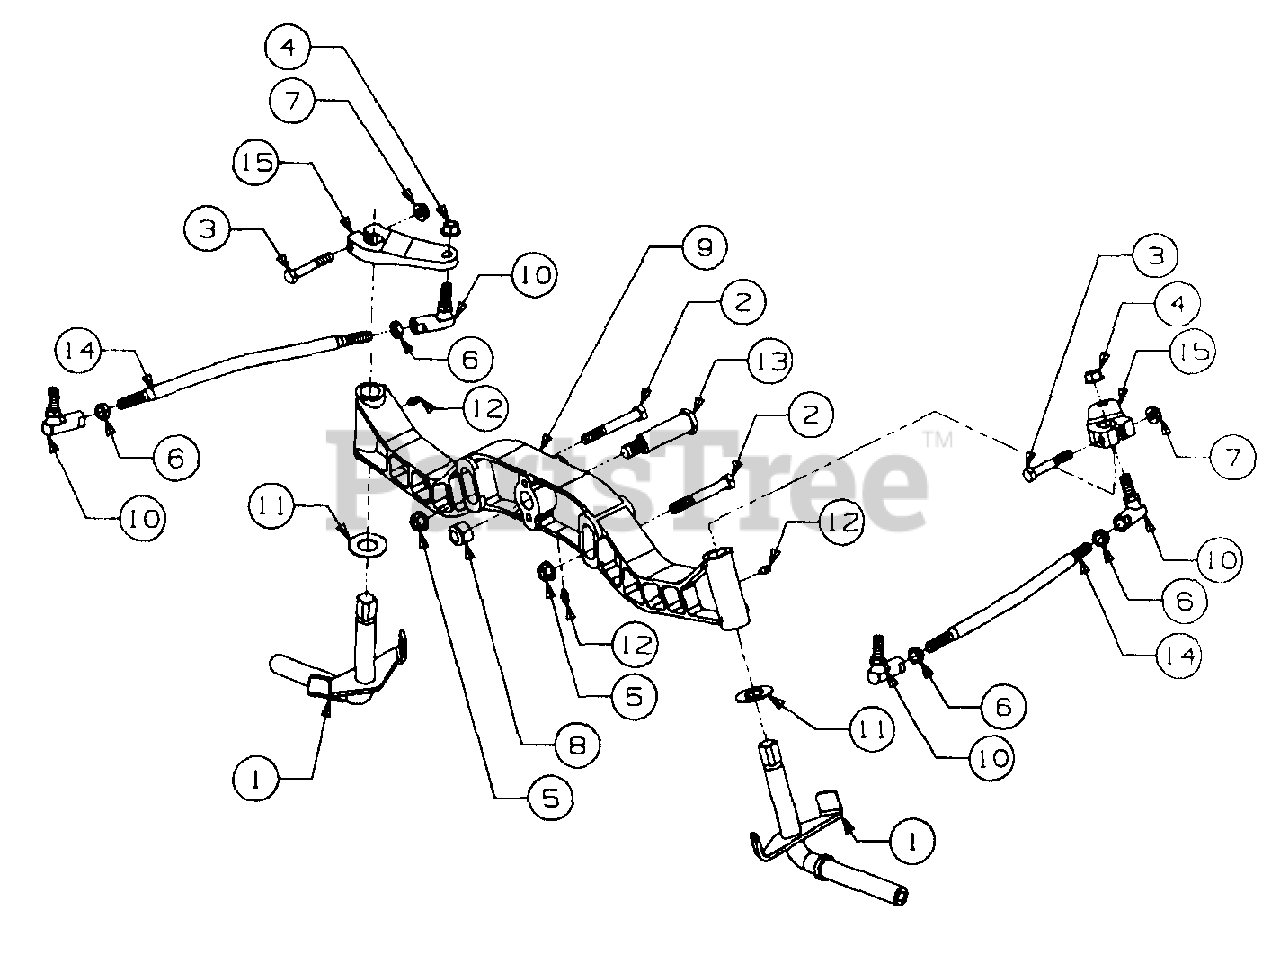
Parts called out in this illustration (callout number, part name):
1	Knuckle Assembly, Steering
2	Screw, Hex Cap, 3/8-16 x 2.75 GR8
3	Screw, Hex Cap, 5/16-18 x 2 GR5
4	Nut, Hex Lock, 3/8-24 GR5
5	Nut, Hex Flanged Lock, 3/8-16
6	Nut, Hex Jam, 3/8-24 GR5
7	Nut, Hex Flange Top Lock, 5/16-18
8	Nut, Hex Top Nylon Lock, 1/2-13
9	Axle, Front Pivot
10	Joint, Ball, 3/8-24
11	Washer, Flat, .760 x 1.49 x .06 Thk.
12	Fitting, Lube, 3/16 Drive Type
13	Bolt, Pivot Shoulder, 3/4 Dia x 2.23
15	Arm, Steering
